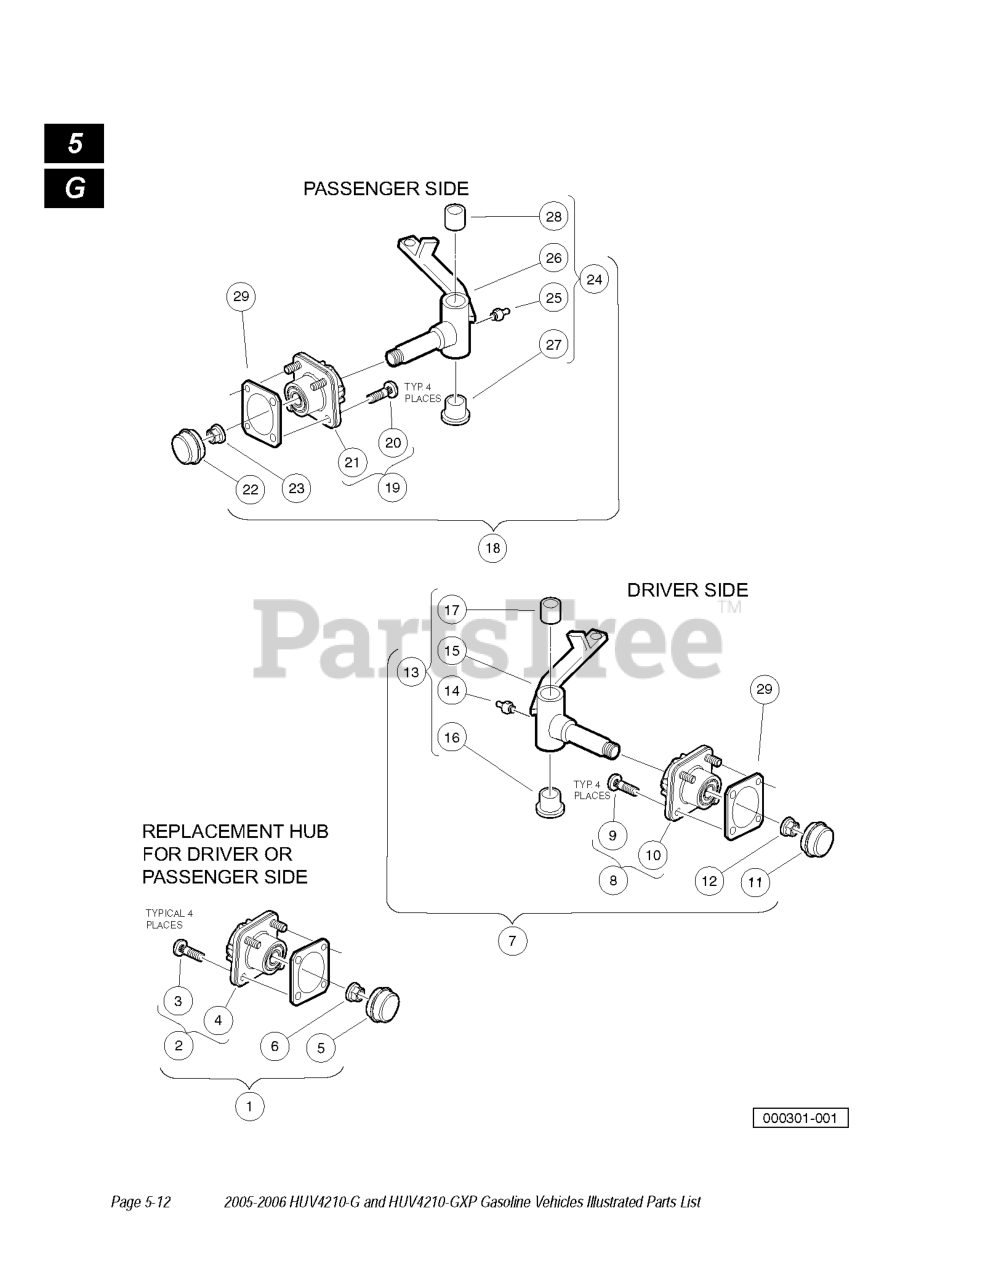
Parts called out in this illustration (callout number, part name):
1	REPLACEMENT KIT, FRONT HUB
3	LUG STUD, 1/2-20 UNF, 4037 STL
5	CAP, FRONT HUB
6	HEX NUT, LOCKING FLANGE, M14X2
9	LUG STUD, 1/2-20 UNF, 4037 STL
11	CAP, FRONT HUB
12	HEX NUT, LOCKING FLANGE, M14X2
13	ASM, SPINDLE, LH
14	FITTING, 1/4-28 THRD FRM GREAS
16	BUSHING, FLANGED BROZE
17	BUSHING BRONZE SPINDLE
20	LUG STUD, 1/2-20 UNF, 4037 STL
22	CAP, FRONT HUB
23	HEX NUT, LOCKING FLANGE, M14X2
24	ASM, SPINDLE, RH
25	FITTING, 1/4-28 THRD FRM GREAS
27	BUSHING, FLANGED BROZE
28	BUSHING BRONZE SPINDLE
29	SPACER, WHEEL
